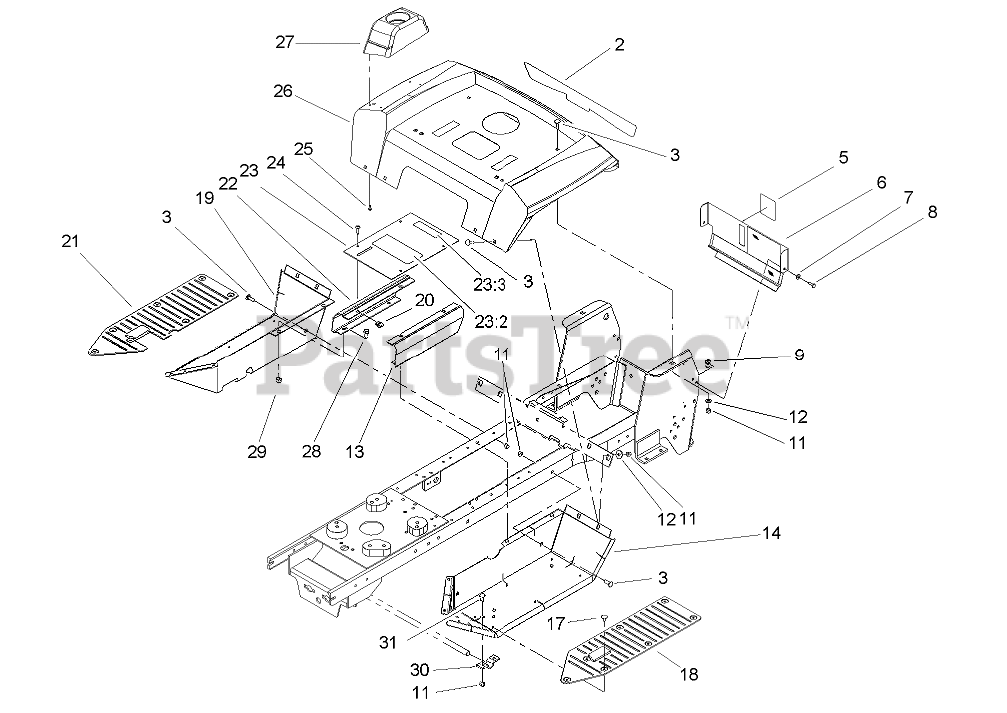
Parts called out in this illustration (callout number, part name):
2	DECAL-FENDER, REAR
3	SCREW-CARR
5	DECAL-LEVEL, FUEL
6	REAR PANEL ASM
7	WASHER-FLAT
8	SCREW-HH
9	NUT-SPEED
11	NUT-LOCK, NI
12	WASHER
13	CHANNEL-SADDLE, LH
14	FOOTREST-LH
17	FASTENER-PANEL
18	FOOTPAD-LH
19	FOOTREST-RH
21	FOOTPAD-RH
22	CHANNEL-SADDLE, RH
23	SADDLE PLATE DECAL ASM
23:2	DECAL-DANGER
23:3	DECAL-INSTRUCTION
24	SCREW-HH
25	SCREW-HHFTF
26	FENDER ASM
27	HOLDER-CUP
28	SCREW-HH
29	NUT-LOCK, NI
30	CLAMP
31	BOLT-CARR
